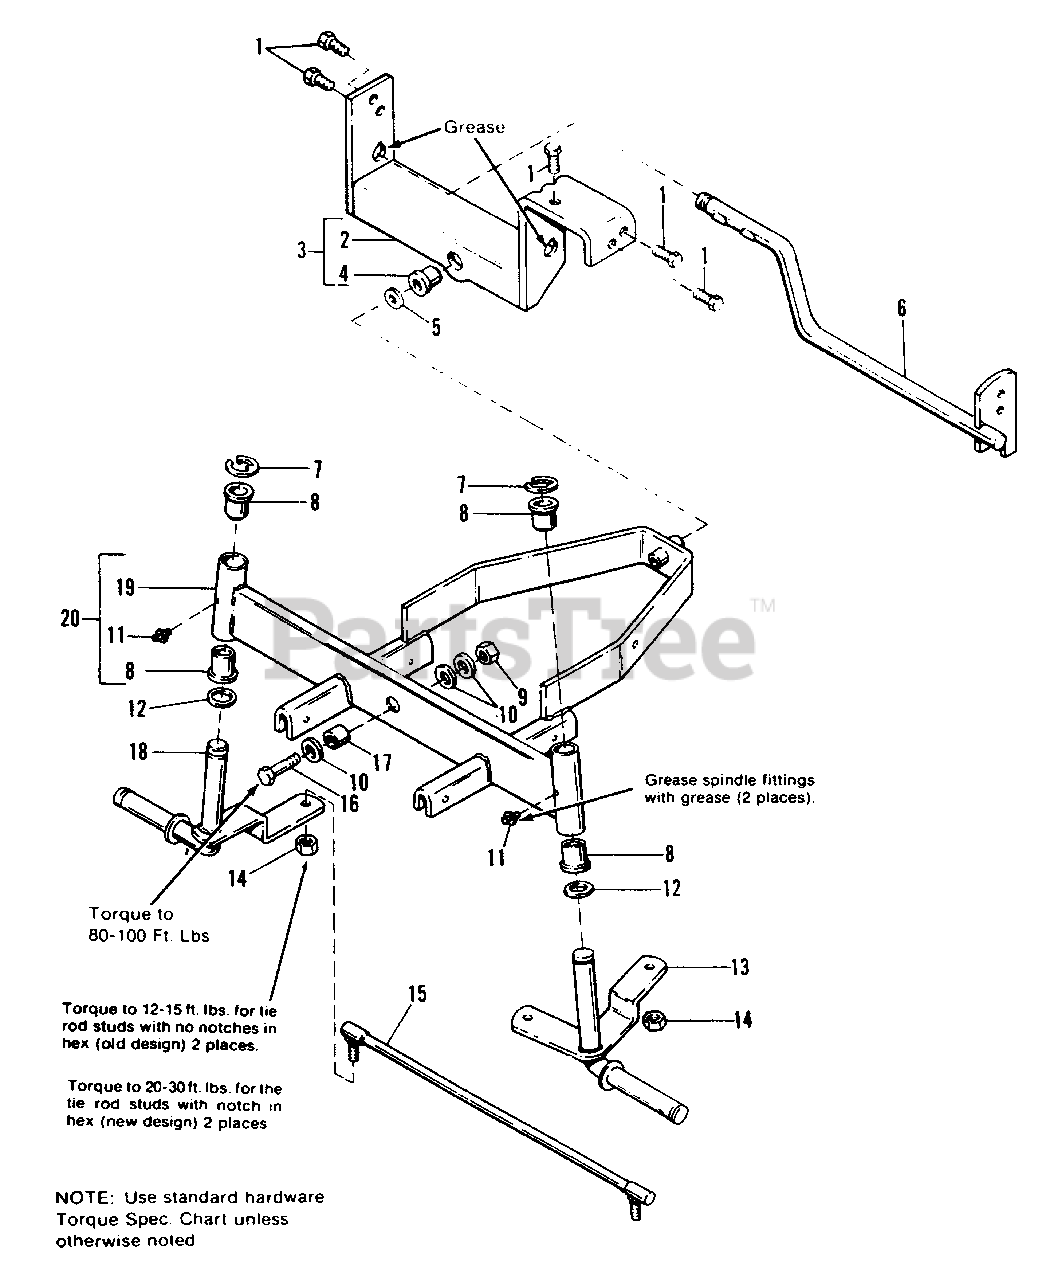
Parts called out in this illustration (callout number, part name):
1	SCREW, Taptite, 5/16-18 x 3/4
3	SUPPORT ASSY., Axle, Rear w/Bushings
5	WASHER, 5/8
6	LEVER ASSY., Brake
7	E-RING, Ext. 3/4 Dia.
9	LOCKNUT, Hex, 1/2-13
10	WASHER, Plain, 9/16
11	FITTING, Grease
13	SPINDLE ASSY., L.H.
14	LOCKNUT, Hex, Gr. B, 3/8-24
15	ROD ASSY., Tie
16	CAPSCREW, Hex, 1/2-13 x 1-1/2
18	SPINDLE ASSY., R.H.
20	AXLE ASSY., Front (6116 & 6118 Only)
20	AXLE ASSY., Front (6108 & 6111 Only)
